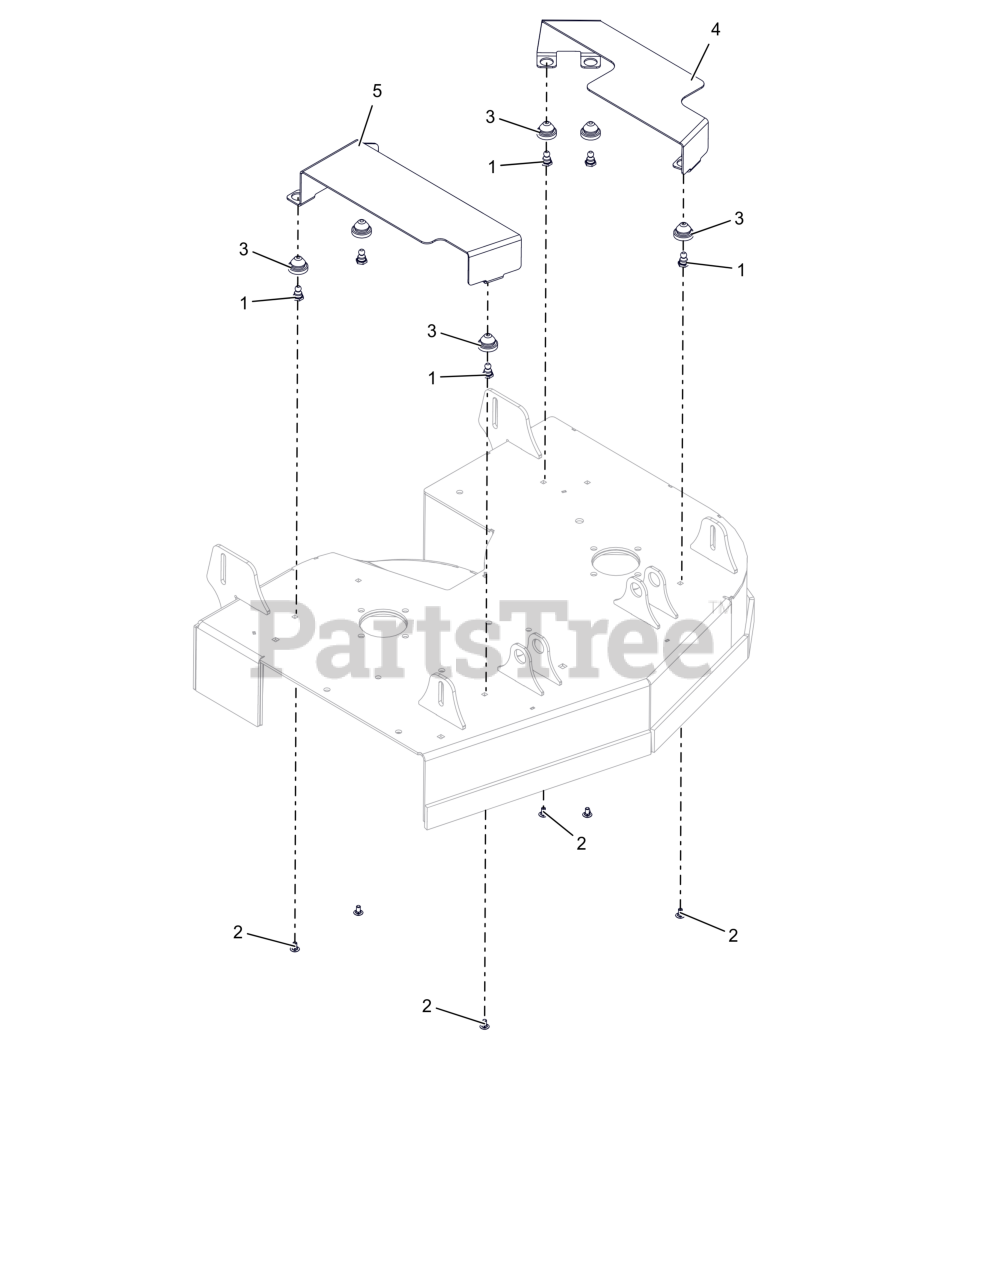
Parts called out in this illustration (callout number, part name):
1	STUD, BALL FEMALE .250-20 THREAD
2	BLT, RHSSN.25-20X.500 G5 ZCC
3	COUPLING, RUBBER PUSH-IN
4	GUARD- 32" DECK LH BELT (RED)
5	GUARD- 32" DECK RH BELT (RED)
